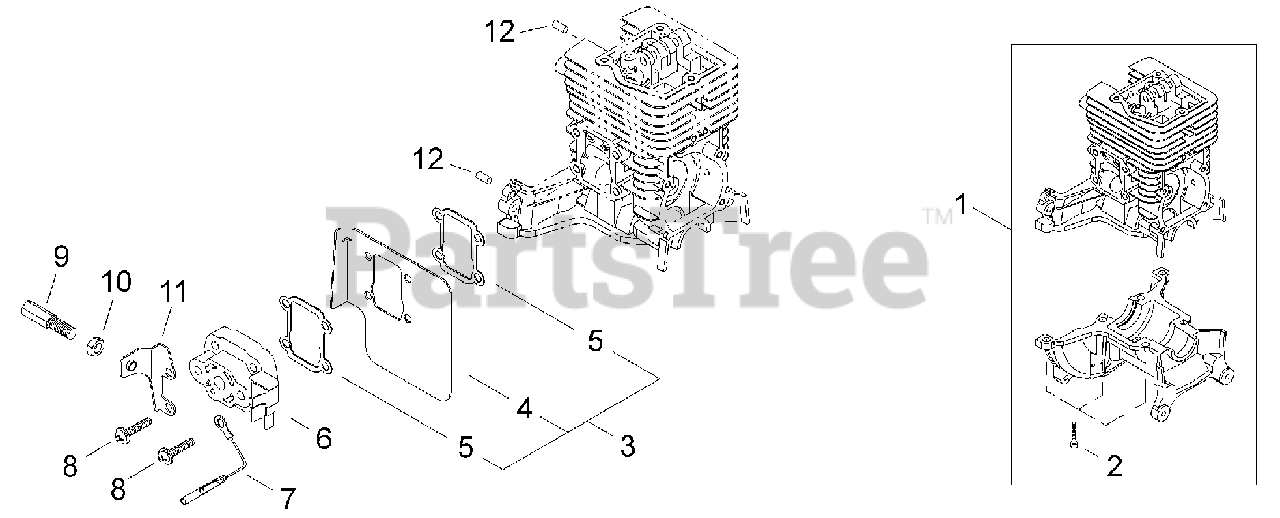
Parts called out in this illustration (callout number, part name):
1	CYLINDER BLOCK SET
2	SCREW - 5X16
3	HEAT DEFLECTOR ASSY
4	DEFLECTOR, HEAT
5	SHIELD, INTAKE
6	INSULATOR
7	LEAD - GROUND
8	SCREW - 5X22
9	NUT, CABLE ADJUST
10	LOCKNUT - 6
11	BRACKET, THROTTLE CABLE
12	PIN - LOCATING
